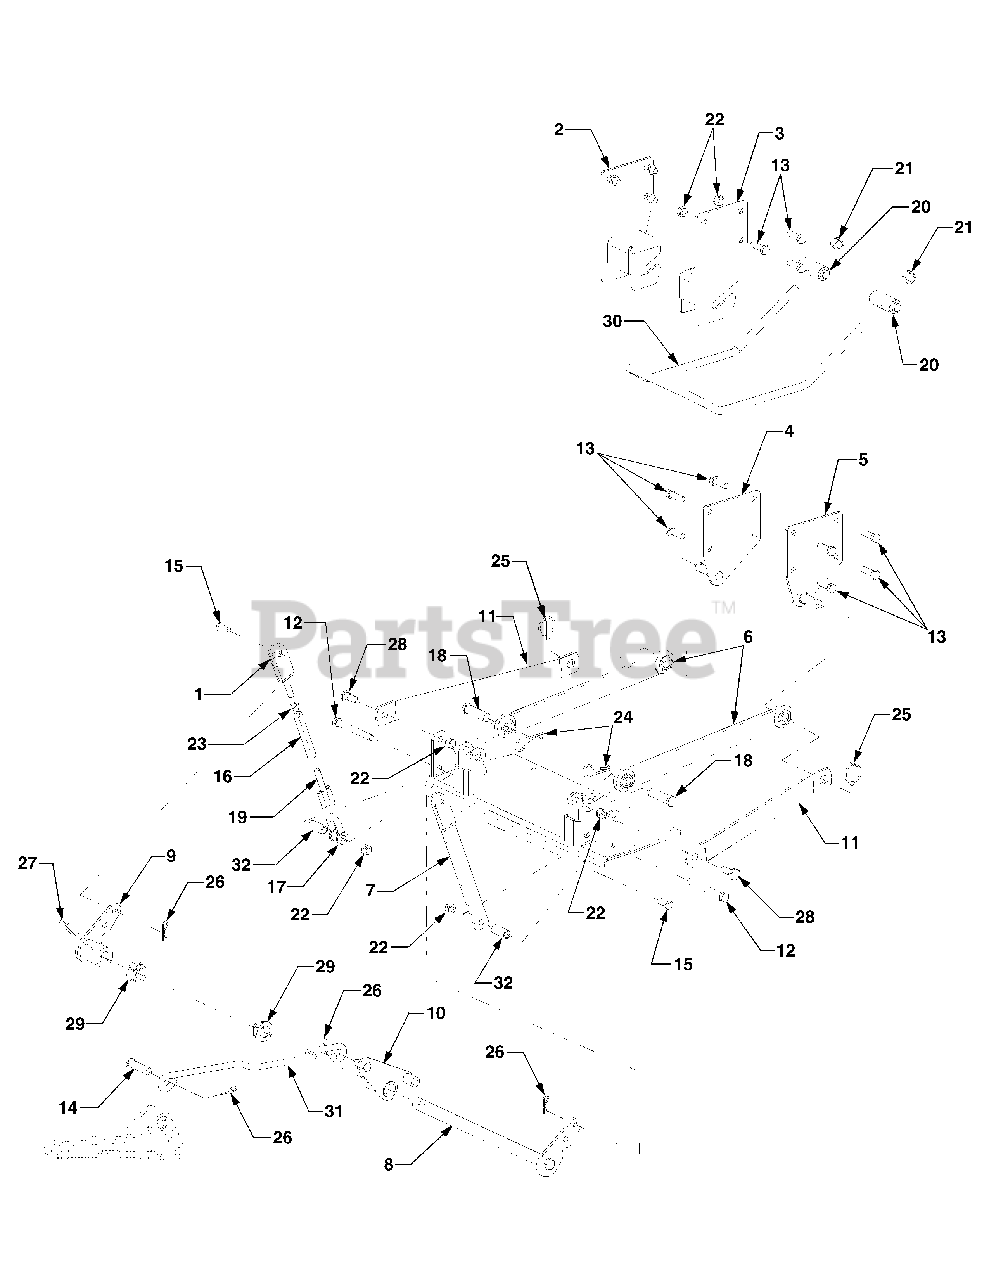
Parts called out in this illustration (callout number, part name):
1	Clevis, Adjustment, 1/2 -13 x 4.76
2	Bracket, Front Hanger LH
3	Bracket,, Front Hanger RH
4	Bracket, Rear Hanger LH
5	Bracket, Rear Hanger RH
6	Link, Deck Lift
10	Plate, Lift Crank
11	Brace, Deck Side
12	Screw, Hex Cap, 1/2-13 x 4.5 GR5
13	Screw, Hex Cap, 1/2-13 x 1.5 GR5
14	Pin, Clevis, .625 x 2.18
15	Pin, Clevis, .5 x 1.18
16	Turn Buckle, Hex Adjustment
17	Clevis, Check Chain
18	Pin, Clevis, 3/4 x 2.5
19	Clevis, Chain
20	Pin, Hanger Rod Mounting
21	Nut, Hex Insert Lock, 5/8-11
22	Nut, Hex Center Lock, 1/2-13
23	Nut, Hex Jam, 1/2-13 GR5
24	Pin, Internal Cotter
25	Pin, Klik
26	Pin, Internal Cotter
27	Pin, Spirol, 5/16 x 1.75
28	Screw, Shoulder, .625 x.36: 1/2-13
29	Bearing, Flange w/Flats
30	Rod, Front Hanger
31	Rod, Crank Lift
32	Spacer, .52 x .87 x 1.57
